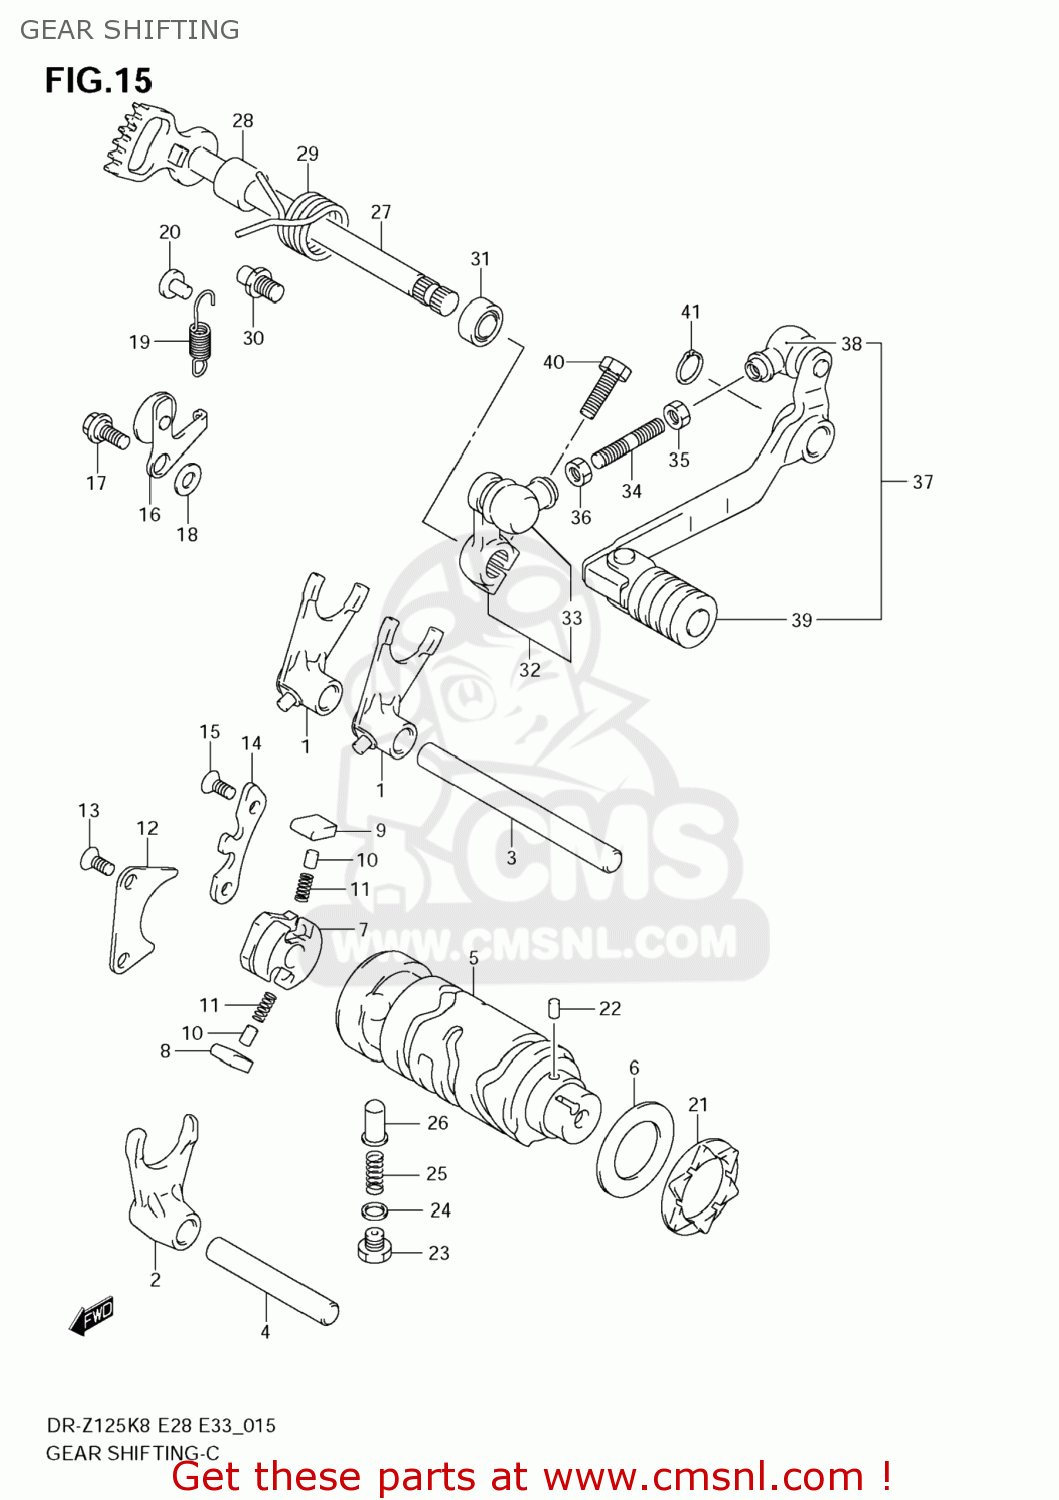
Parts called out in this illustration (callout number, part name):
1	FORK,GEAR SHIFT NO.2
2	FORK,GEAR SHIFT NO.3
3	SHAFT,GEAR SHIFT FORK(L:109)
4	SHAFT,GEAR SHIFT FORK NO.2
5	CAM,GEAR SHIFT
6	SHIM(25X40X1)
7	GEAR,GEAR SHIFT CAM DRIVEN
8	PAWL,GEAR SHIFT NO.1
9	PAWL,GEAR SHIFT NO.2
10	PIN(5X8)
11	SPRING
12	LIFTER,GEAR SHIFT POLE
13	SCREW(6X12)
14	GUIDE,GEAR SHIFT CAM
15	SCREW(6X12)
16	STOPPER,GEAR SHIFT CAM
17	BOLT(6X14.6)
18	WASHER
19	SPRING
20	RIVET
21	PLATE,GEAR SHIFT CAM STOPPER
22	PIN
23	PLUG(14X12)
24	GASKET(13.8X18.8X4.8) (NAS)
25	SPRING
26	STOPPER,GEAR SHIFT CAM NO.2
27	SHAFT,GEAR SHIFT
28	SPACER(12X20X15.3)
29	SPRING
30	STOPPER,GEAR SHIFT ARM
31	SEAL,OIL (12X22X9)
32	ARM,GEAR SHIFT LINK
33	COVER,DUST
34	ROD,GEAR SHIFT LINK
35	NUT
36	NUT
37	LEVER ASSY,GEAR SHIFT
38	COVER,DUST
39	RUBBER,GEAR SHIFT PEDAL
40	BOLT
41	CIRCLIP
